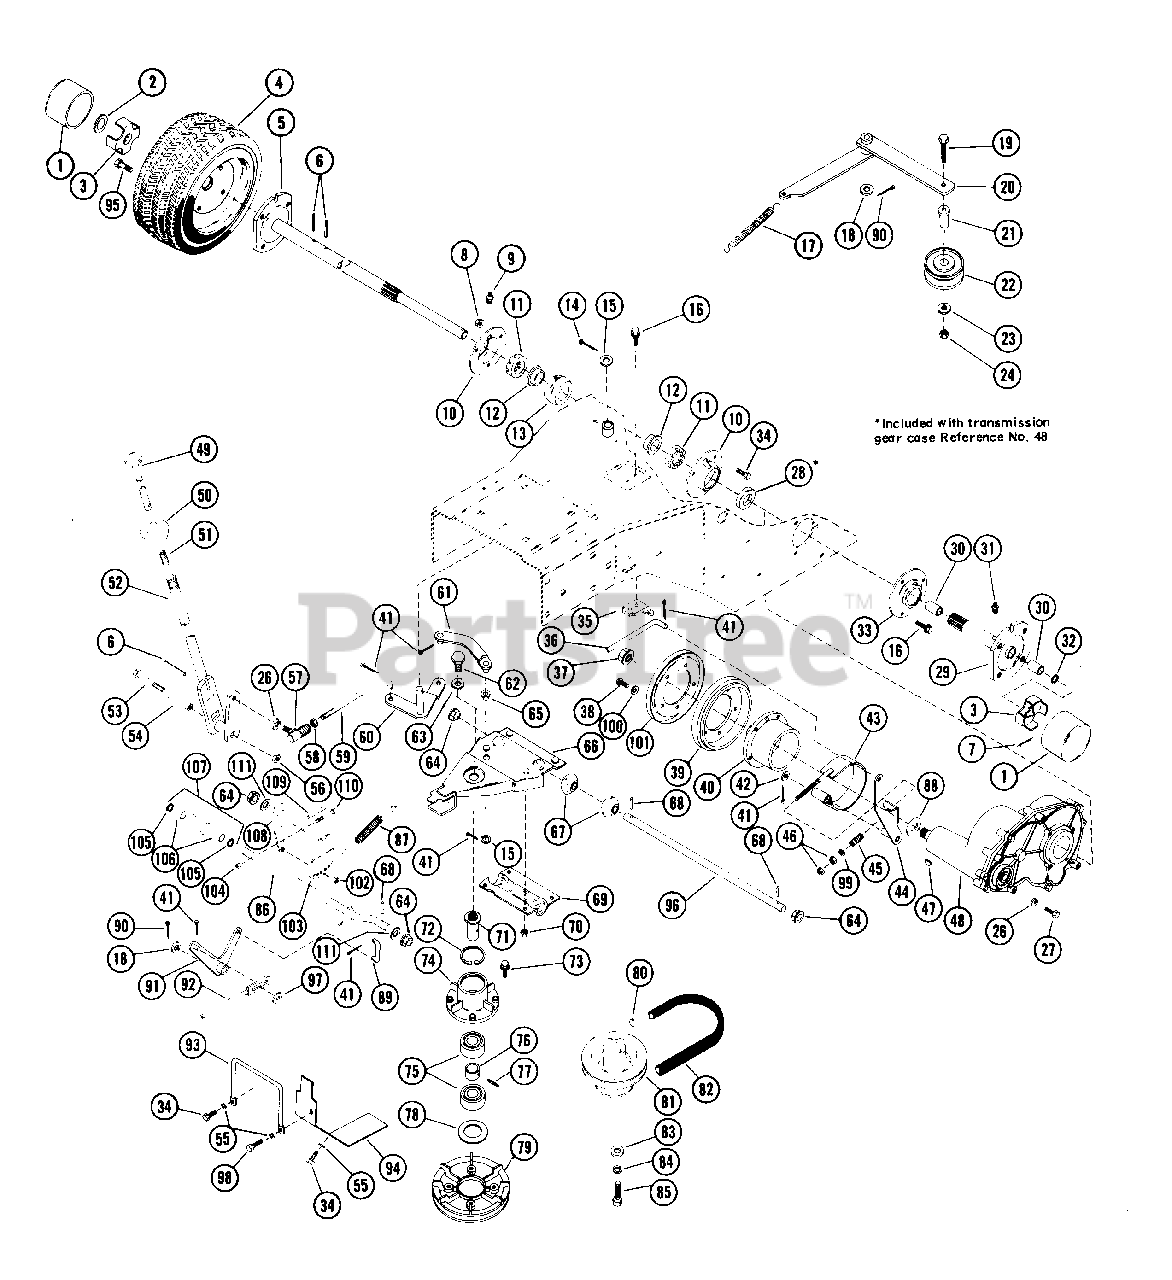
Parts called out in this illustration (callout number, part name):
1	HUB CAP
2	PUSHNUT
3	SPINDLE CUP
4	TERRA TIRE & WHEEL ASSEMBLY
4	WHEEL
5	R H AXLE SHAFT
6	PIN-ROLL .188X1.50
7	PIN-COTR .12 X 1.25 PL
8	NUT-LK-FLG .250-20 PL
9	ZERK FITTING
10	BEARING FLANGE
11	ADJUSTMENT SPACER
12	BSHG-FLG 1.125X1.31X.50X1.62BR
13	SPHERICAL BUSHING
14	PIN-COTR .12X1.0 PL
15	WSHR-FL-STL .505X.880X.072 PL
16	BLT-SCRHFWH .25-20X.62 PL
17	SG-TENS 6.25 FREE LENGTH
18	WSHR-FL-STL .505X1.000X.062
19	BLT-HEX .31-18X1.25 PL GR2
21	SPCR, BRG .315X.50X.688X.281
22	IDLER
23	WSHR-FL-STL .38X.875X.083 PL
24	NUT-LK .312-18 GR A PL
25	O-RING 2.250X2.234X.139
26	WSHR-LK .312X.097 PL HVY
27	BLT-HEX .31-18X1.50 PL GR2
28	SEAL 1.125X1.624X.250
29	L H AXLE ASSEMBLY
30	BSHG-SLV .750X.814X .750 BRZ
31	HYDRAULIC DRIVE FITTING
32	O-RING .755X.950X.097
33	SEAL 1.125X2.496X.380
34	BLT-HEX .25-20X.50 PL GR2
35	NEUTRAL STOP
36	BRAKE ROD
37	NUT-LK-NYL.625-18 PL
38	BLT-HEX .31-18X.50 PL GR2
39	FRICTION DISC
40	FRICTION DISC HUB
41	PIN-COTR .09X.75 PL
42	WSHR-FL-STL .380X.626X.033
43	BRAKE BAND
44	BRAKE LEVER
45	SG-COMP .105X.585X.75
46	NUT-HEX .312-18
47	KEY-WDRF .188X.875X.375 SAE11
48	GEAR CASE ASSEMBLY
49	SHIFT CONTROL ROD
50	SHIFT BALL
51	SG-COMP ??X.44X?? WLD 10
52	SHIFT LEVER
53	BLT-HEX .38-16X2.50 PL GR2
54	SHIFT SPACER
55	WSHR-LK .250X.077 HVY PL
56	NUT-LK-CTR .375-16 GR A PL
57	SNAP IN BALL JOINT
58	NUT-HEX .312-24 PL
59	SHIFT ROD
60	SHIFT LEVER
61	SHIFT LINK
62	SPINDLE STUD
63	WSHR-LK-EXT .500X.040 MED
64	FLANGE BUSHING
65	BSHG-FLG .372X.500X.312X.625NY
66	MTG PLATE
67	BEARING
68	PIN-ROLL .188X1.13
69	BEARING RETAINER
70	NUT-LK-CTR .250-20 PL
71	SPINDLE
72	SNAP RING KIT
73	BLT-SERHFWH .25-20X.75 PL
74	SPINDLE HOUSING
75	BRG-BALL .751X1.78X.61
76	SPACER .753X1.000X.457
77	PIN-ROLL .188X1.00
78	WSHR-FL-STL 1.375X2.125X.075
80	KEY-STR .25X2.0X.25
81	SHEAVE
82	V-BELT, SAE 380-RAW EDGE
83	WSHR-FL-STL .438X1.125X.19
83	WSHR-FL-STL .505X1.140X.250
84	WSHR-LK .375X.115 HVY PL
84	WSHR-LK .438X.133 HVY
85	BLT-HEX .38-24X1.25 BLKO GR5
85	BLT-HEX .44-20X1.25 GR5
87	SG-COMP .062X.438X6.625
88	WSHR-FL-STL .627X.990X.032
89	LINK PIN
90	PIN-COTR .09X1.0 PL
91	CLUTCH LEVER
92	CLUTCH ROD
93	BELT GUIDE
94	SPLASH GUARD
95	BLT-WHL .50-20X.75 GR5 PL
96	HINGE SHAFT
97	WSHR-FL-STL .382X.812X.023 PL
98	BLT-HEX .25-20X.75 PL GR2
99	WSHR-FL-STL .323X.625X.062 PL
100	WSHR-LK-INT .313X.030 PL
102	NUT-KEPS 8-32
103	STOP ADJUSTMENT
104	NUT-LK TOP .250-20 PL
105	SEAL .625X.875X.125
106	BSHG-SLV .625X.750X.500 BR
107	ROLLER ASSEMBLY
109	PIN-GRV .250X1.25 TP A
110	BLT-HEX .25-20X1.50
111	WSHR-FL-STL .630X1.005X.062 PL
